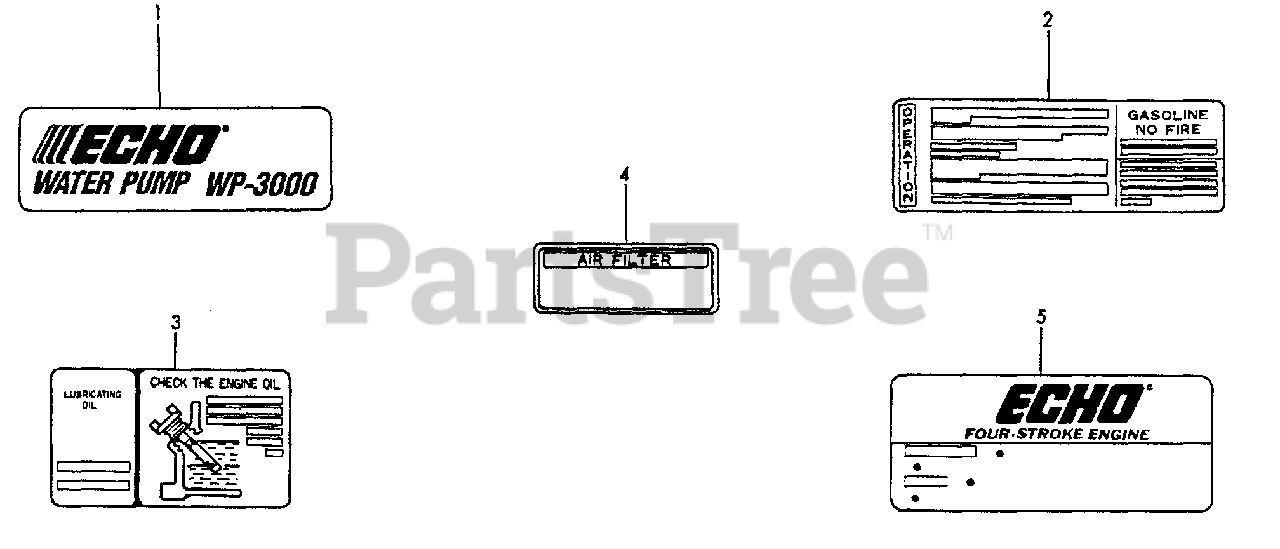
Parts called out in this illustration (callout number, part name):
1	LABEL - MODEL WP3000
2	LABEL, OPERATION
3	LABEL, OIL
4	LABEL - AIR FILTER
5	LABEL, ECHO
